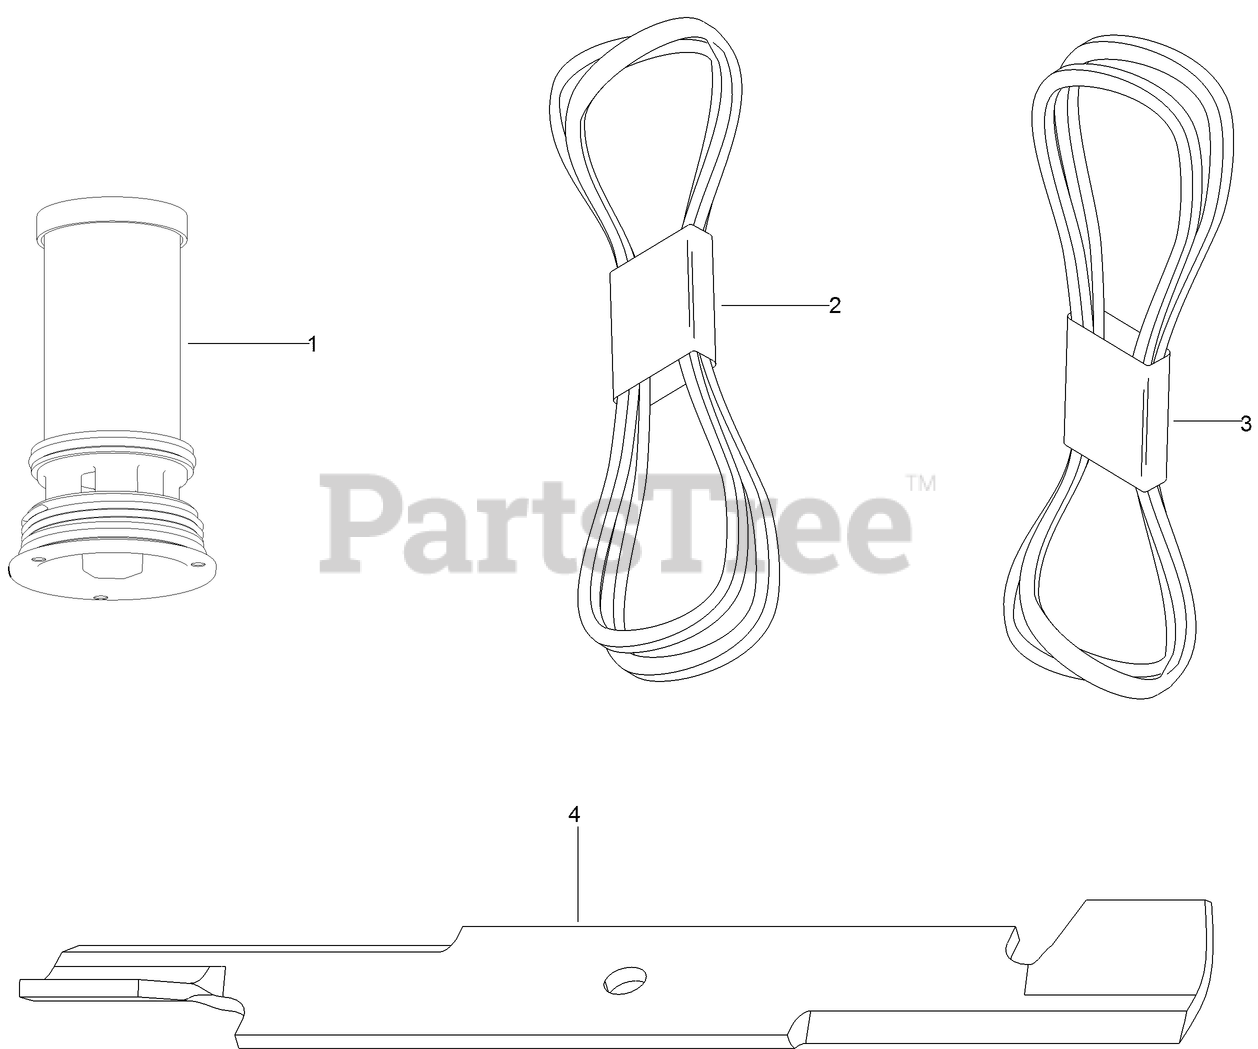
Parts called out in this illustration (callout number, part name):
1	FILTER-HYDRO
2	BELT-V
3	BELT-V
4	BLADE-16.5 INCH (HIGH FLOW)
